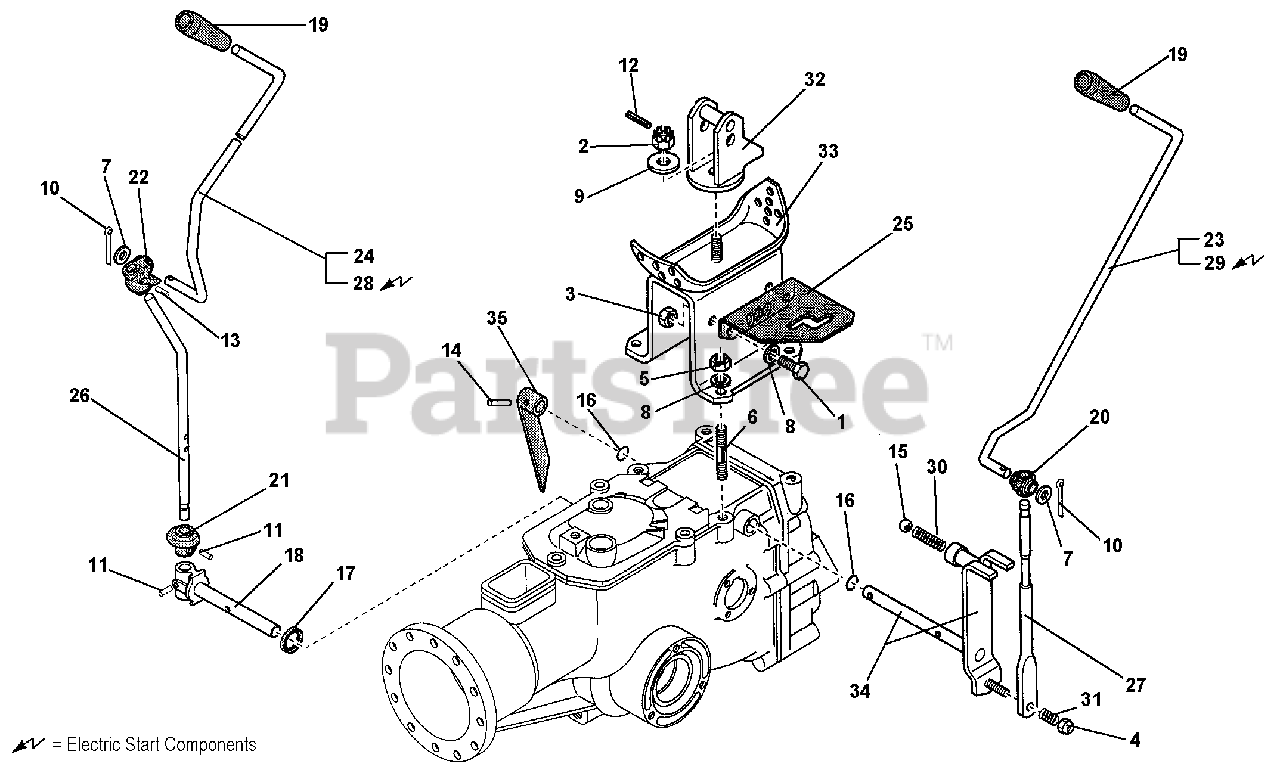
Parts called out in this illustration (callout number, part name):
1	SCREW, M8X20
2	NUT, CASTLE, M12
4	NUT, SELF LOCKING, M8
6	STUD, M8X38X14X20
7	WASHER, M10.5
8	SUPER WASHER
9	LOCK WASHER, M13
11	PIN, LOCKING, M4X20
12	PIN, LOCKING, M3X22
13	PIN, LOCKING, M4X24
14	LOCKING PIN, 6X20 SPIRAL
15	BALL, 15/32"
16	OIL SEAL, 14X18X2.5
17	OIL SEAL, 14X22X4
20	ARTICULATOR
21	PTO STOP RING
22	PTO ARTICULATION
23	SPEED CONTROL ROD, 710, RECOIL START
24	PTO CONTROL ROD, RECOIL START
25	GEAR SELECTOR, 710
26	PTO CONTROL LEVER
27	SPEED CONTROL LEVER
28	PTO CONTROL ROD, ELECTRIC START
29	SPEED CONTROL ROD, 710, ELECTRIC START
32	HANDLE BAR SUPPORT
33	HANDLE BAR ANCHOR
34	SPEED CONTROL LEVER, 710
35	PTO LOCKOUT LEVER, 710
